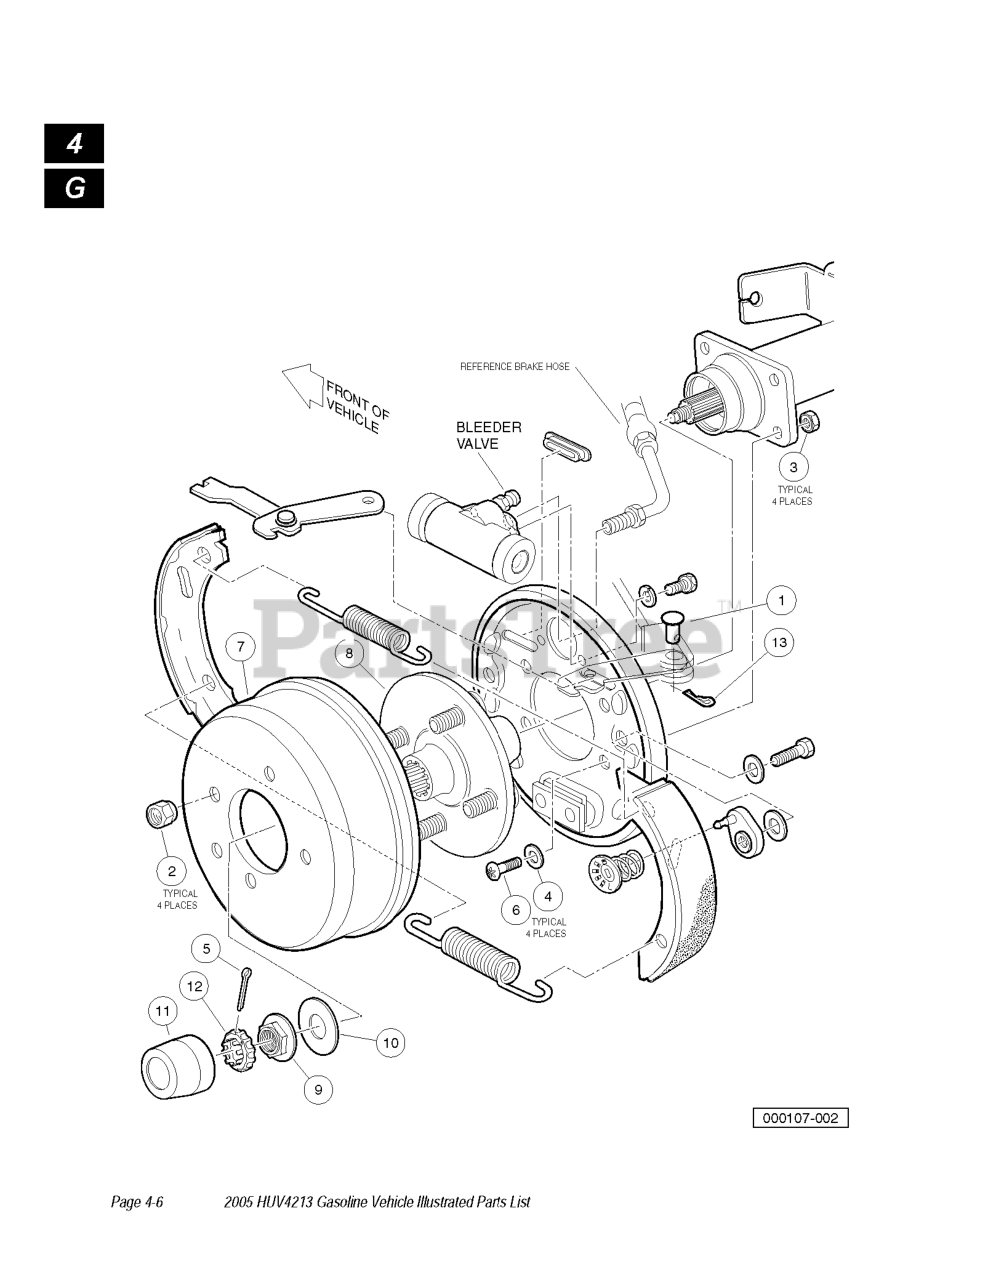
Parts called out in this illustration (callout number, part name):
2	NUT 1/2-20 LUG
4	WASHER, 5/16 HARDENED
5	PIN-COTTER - .312 X 1.25"
6	SCREW, 5/16-24 X 1.0 TORX HD
7	BRAKE DRUM, FE400 REAR
8	WHEEL BOLT FLANGE
9	NUT - AXLE FLANGE
10	WASHER - AXLE
11	CENTER CAP, RUBBER
12	LOCKING CAP, NUT
13	PIN, BOW TIE LOCKING - .072
